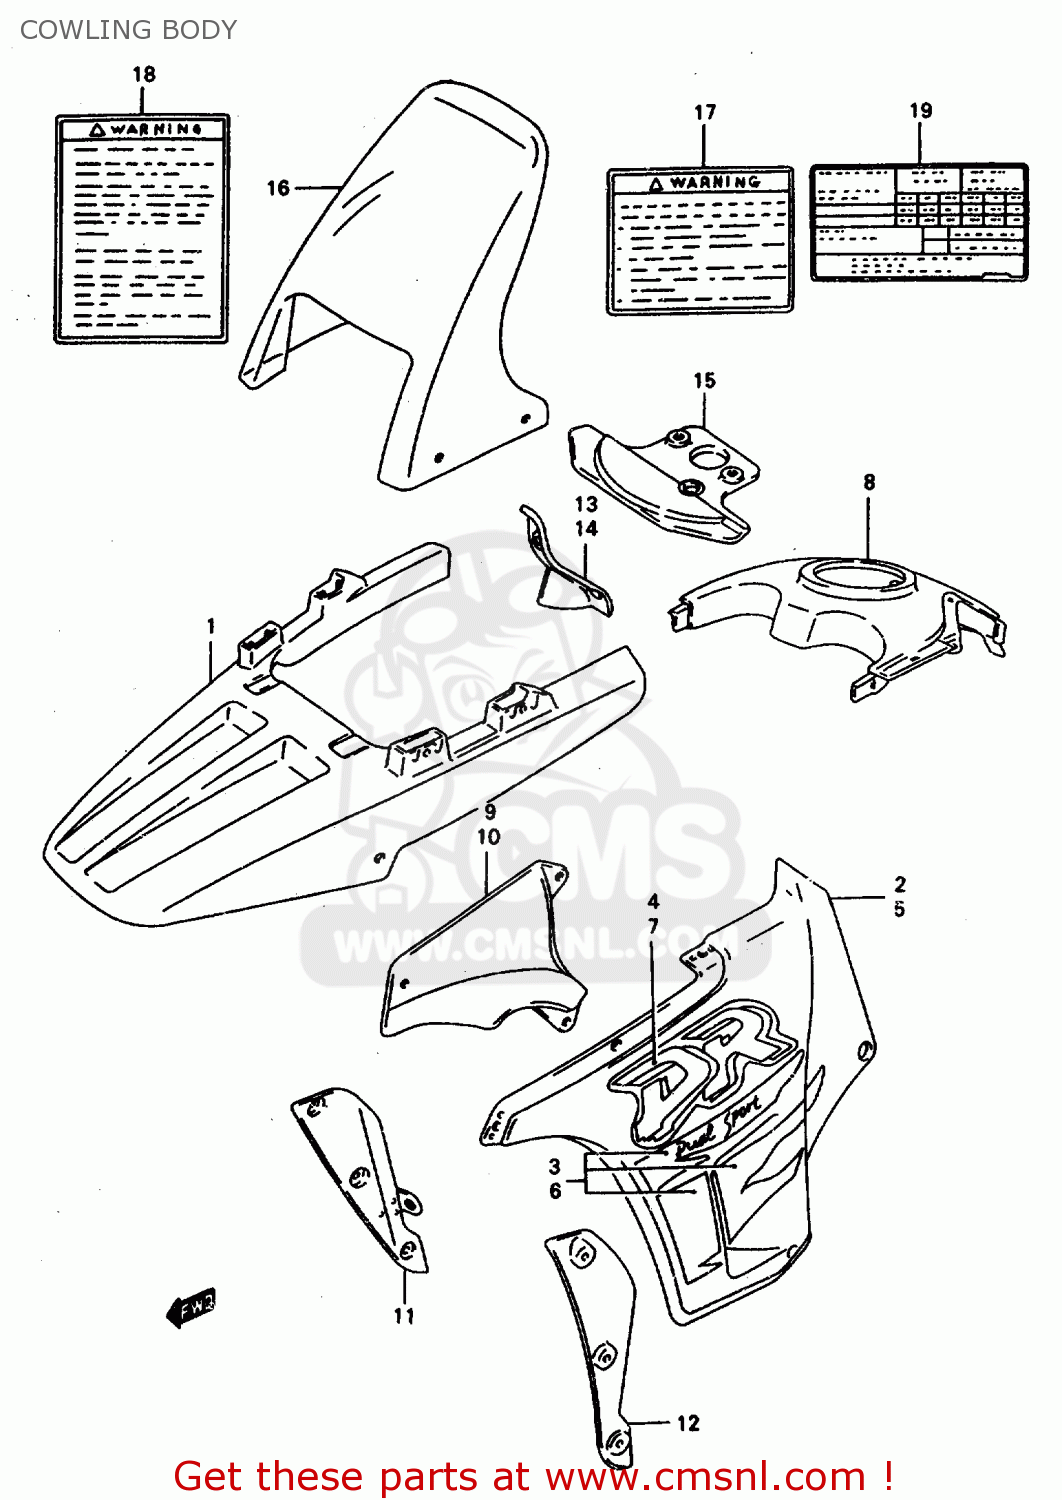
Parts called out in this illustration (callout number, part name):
1	COWLING ASSY,FR
2	COWLING ASSY,SIDE,R
3	TAPE SET,COWL SIDE,R
4	EMBLEM,COWLING SIDE
5	COWLING ASSY,SIDE,L
6	TAPE SET, SIDE LH
7	EMBLEM,COWLING SIDE
8	COWL ,UPPER
9	PANEL,COWLING,INNER,R
10	PANEL,COWLING,INNER,L
11	COWLING, SIDE FRONT RH
12	COWLING,SIDE FR,L
13	PANEL,COWLING,R
14	PANEL,COWLING,L
15	COVER COWLING,FRONT LOWER
16	WINDSCREEN
17	LABEL,WARNING
18	LABEL (WARNING SCREEN)
19	LABEL, TIRE AIR PRESSURE
